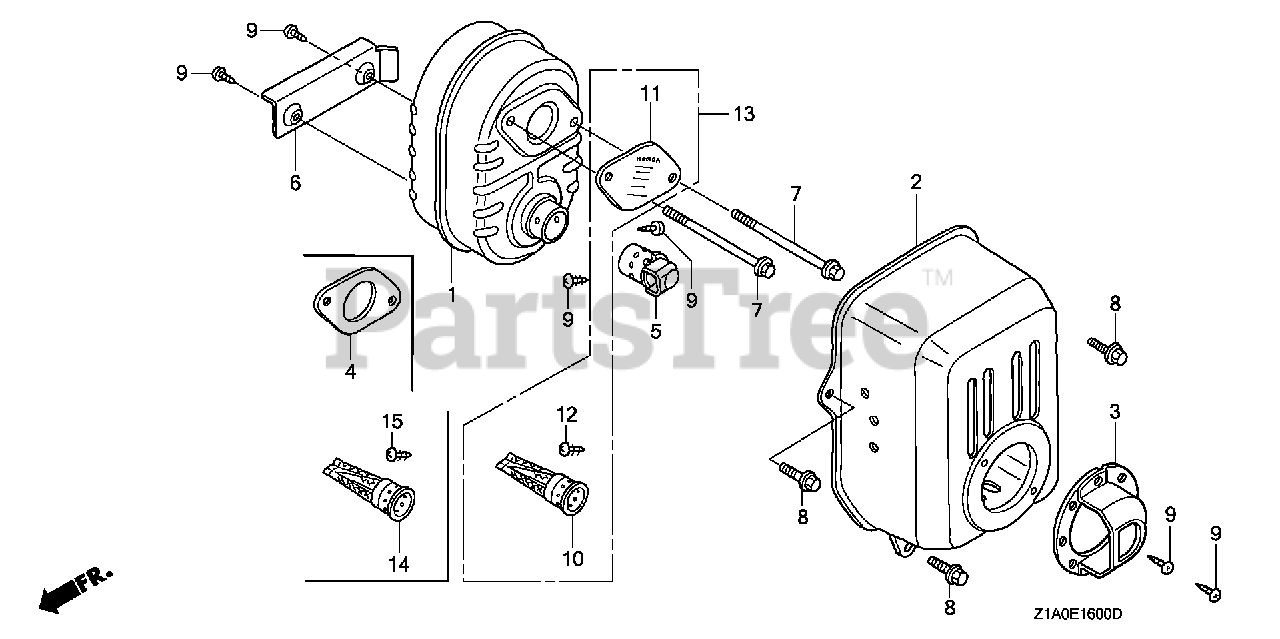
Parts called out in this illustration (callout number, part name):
1	MUFFLER
2	PROTECTOR, MUFFLER
4	GASKET, MUFFLER
6	SHROUD, MUFFLER
7	BOLT, FLANGE (6X79) (CT200)
8	BOLT, FLANGE (6X12) (CT200)
9	SCREW, TAPPING (4X6) (TO INSTALL OPTIONAL SPARK ARRESTER)
10	ARRESTER, SPARK (TO 1207644)
11	PLATE, ARRESTER NUMBER (TO INSTALL OPTIONAL SPARK ARRESTER)
12	SCREW, TAPPING (4X6) (TO INSTALL OPTIONAL SPARK ARRESTER)
13	ARRESTER KIT, SPARK
